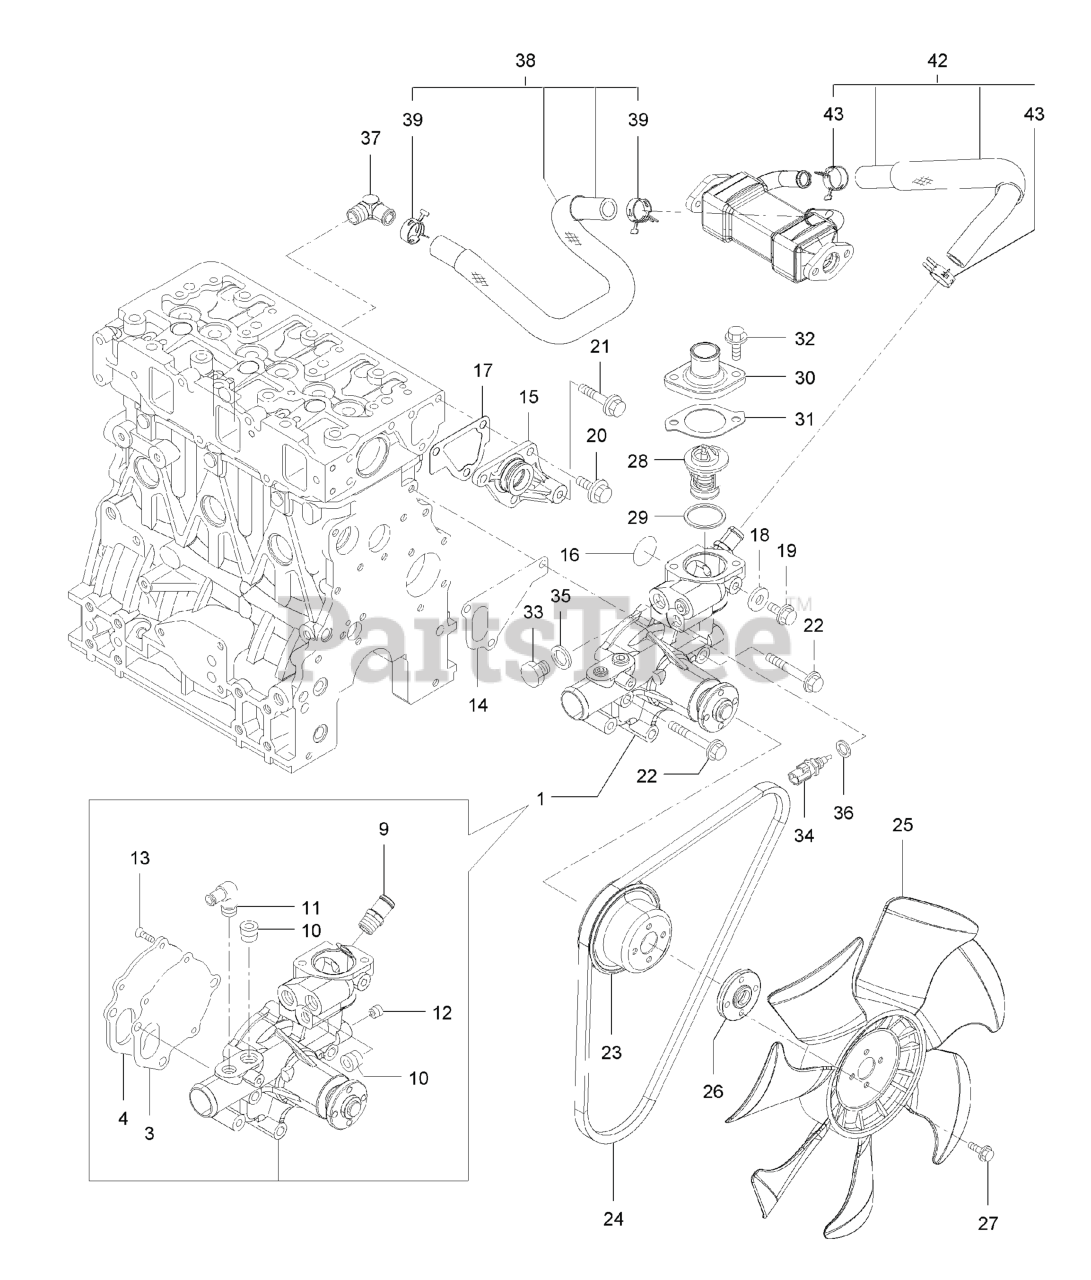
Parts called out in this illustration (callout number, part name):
1	WATER PUMP ASM
20	BOLT
23	V-PULLEY
28	THERMOSTAT
34	SENSOR-THERMOSTAT, CW
36	WASHER-SEAL
38	E G R-C PIPE ASM
39	Clip-Hose
42	CW PIPE ASM
43	Clip-Hose
